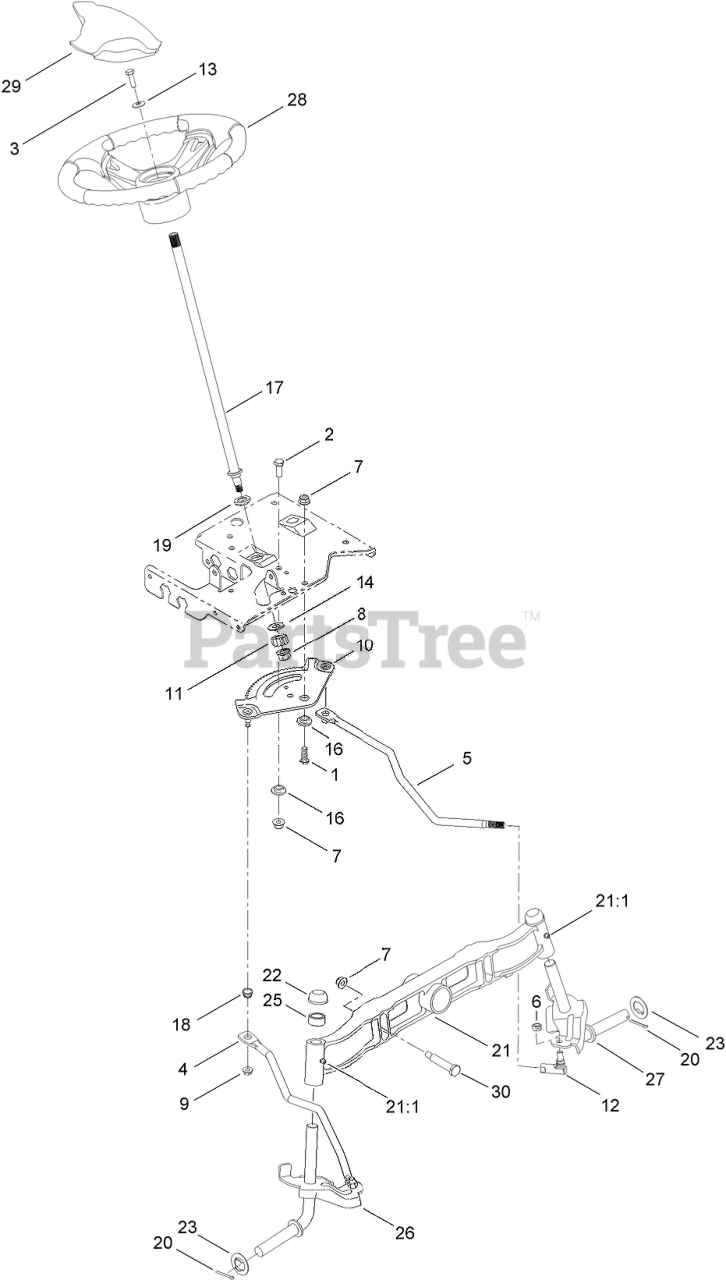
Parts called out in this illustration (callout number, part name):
1	SCREW-HH
2	SCREW-HH
3	SCREW-HH
4	LINK-DRAG, RH
5	LINK-DRAG, LH
6	NUT-HEX, LOCK
7	NUT-LOCK, FLANGE
8	NUT-LOCK, FLANGE
9	NUT-LOCK, FLANGE
10	GEAR-STEERING
11	GEAR-PINION, STEERING
12	BALL JOINT ASM
13	WASHER-FLAT
14	WASHER-FLAT
16	SPACER-SHOULDER
17	SHAFT-STEERING
18	BUSHING
19	BEARING-FLANGE, HEX
20	PIN-COTTER
21	PIVOT-AXLE, CAST IRON
21:1	FITTING-GREASE
23	WASHER-FLAT
25	SPACER
26	RH AXLE ASM
27	LH AXLE ASM
28	WHEEL-STEERING, SOFTGRIP
29	COVER-WHEEL, STEERING
30	BOLT-SHOULDER
